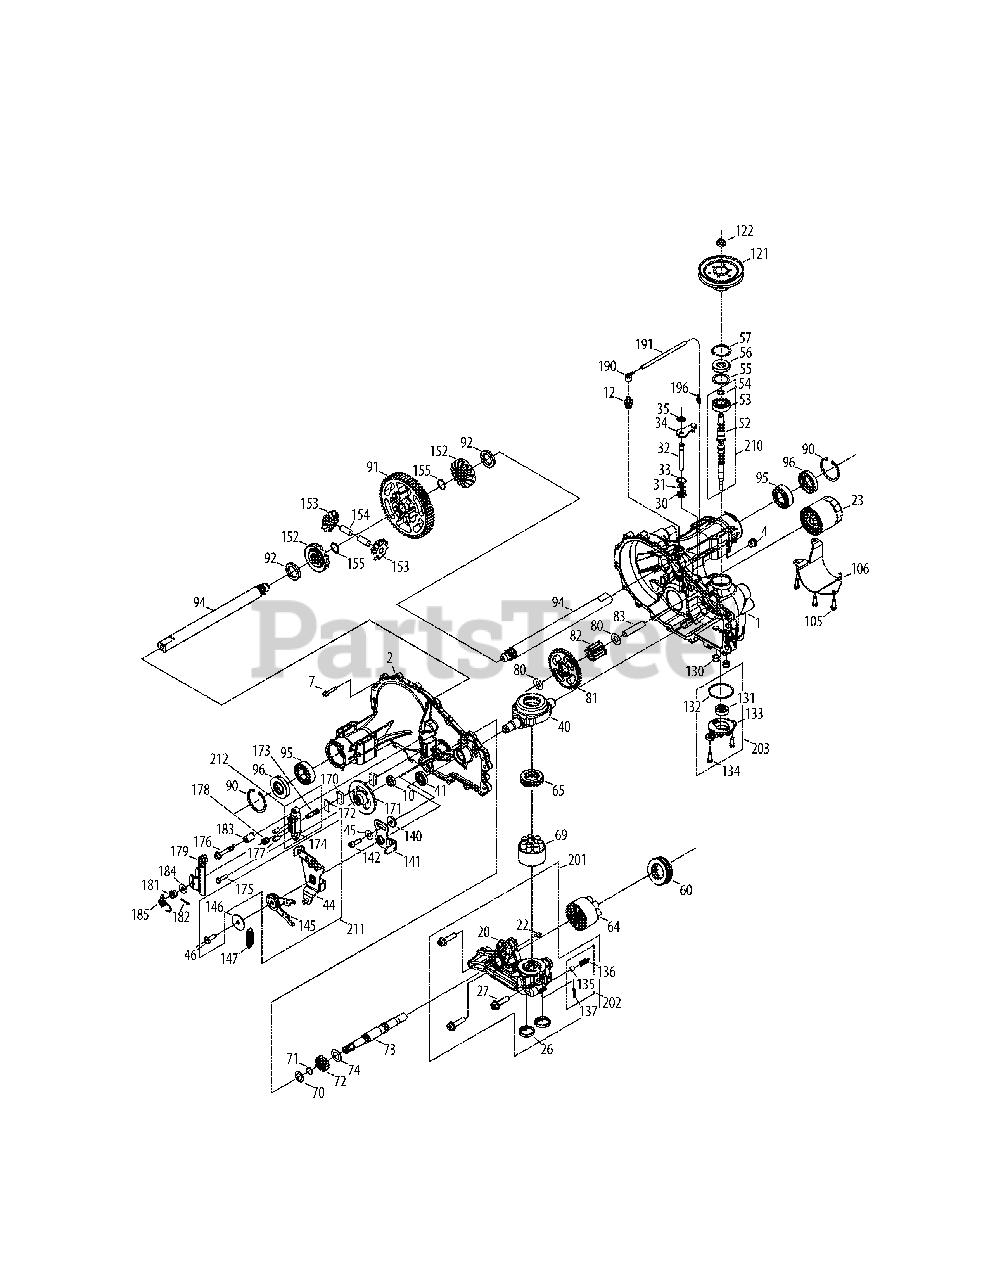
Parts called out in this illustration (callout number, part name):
1	Kit, Housing, Main
1	Housing, Main
1	Pin, Standard Headless
1	Bushing, .624 x .719 x .562
1	Bushing, .865 x .985 x .790
1	Bearing, Flange 1.0 x 1.376 x .99
2	Kit, Housing, Side
2	Housing, Side
2	Bushing, .624 x .729 x .562
2	Bushing, .865 x .985 x .790
2	Bearing, Flange 1.0 x 1.376 x .99
4	Plug, 9/16-18 (Metal)
006	Pin, Standard Headless
7	HFHCS 1/4-20 x 1.25
10	Seal, Lip .625 x 1.0
010	Seal, Lip .625 x 1.0
12	Assembly, Fitting, Metal
020	Center Section, LH, CHRG
22	Plate, Bypass
022	Plate, Bypass
23	Filter, Oil
024	Check Plug
025	Check Plug
26	Seal, Plug 1.250 x .250
026	Seal, Plug 1.250 x .250
27	HFHCS 3/8-16 x 1.5 (Patch)
027	HFHCS 3/8-16 x 1.5 (Patch)
30	Seal, Lip .375 x .75 x .25
030	Seal, Lip .375 x .75 x .25
31	Ring, Retaining .375 External
031	Ring, Ret .375 External
32	Rod, Bypass
33	Ring, Retaining .750 Internal
033	Ring, Ret .750 Internal
34	Arm, Bypass
35	Ring, Retaining .375 Internal
035	Ring, Ret .375 External
40	Trunnion, Swashplate
41	Seal, Lip 18 x 32 x 7
041	Seal, Lip 18 x 32 x 7
044	Arm, Control
45	Washer, .24 x .88 x .05
46	TWHCS 5.16-24 x 1.00 (Patch)
046	TWHCS 5.16-24 x 1.00 (Patch)
046	Screw 5/16-24 x 1.00 (Patch)
052	Shaft, Input
053	Brg, Ball 17 x 40 x 12 Open 6203
054	Ring, Ret Wire .561 ID
55	Washer, 1.23 x 1.56 x .04
56	Seal, Lip 17 x 40 x 17
056	Seal, Lip 17 x 40 x 7
57	Ring, Retaining 1.575 Internal
057	Ring, Ret 1.575 Internal
60	Bearing, Thrust
64	Assembly, Cylinder Block, 16cc
65	Bearing, Thrust Ball 30 x 52 x 13
69	Assembly, Block 7 Piston
70	Washer, .63 x 1.0 x .05
71	Ring, Retaining .625 External
071	Ring, Ret .625 x External
72	Gear, 14T
73	Shaft, Motor
74	Washer, .72 x 1.16 x .04
80	Washer, .5 x 1.0 x .03
81	Gear, 45T
82	Gear, 11T
83	Pin, Jackshaft
90	Ring, Retaining 2.06 Internal
090	Ring, Ret .206 Internal
91	Gear, 60T
92	Spacer, 1.04 x 1.65 x .22
94	Shaft, Axle 1.00 x 13.37, DD
95	Bearing, Ball 1.0 x 52 x 15
96	Seal, Lip 25 x 52 x 10 TC (Gray)
096	Seal, Lip 25 x 52 x 10 TC (Gray)
105	HFHCS 1/4-20 x .75
106	Guard, Filter, LH
121	Pulley, 4.0"
122	Hex Lock Nut 1/2-20 (Nylon Insert)
123	Screw Hex 1/4-20 x .875
130	Tube, Connecting
131	Gerorter Assembly (1.9cc/REV)
132	O-Ring - 137, .103 x 2.050
133	Cover, Charge Pump
134	Screw, Pan Head 1/4-20 x .75
135	Ball, Steel 7/16"
136	Spring, Relief .42 x .75
137	Pin, Spring .125 x .875
140	Spacer, .320 x 1.005 x .179
141	Assembly, RTN, Neutral Arm
142	SHCS 5/16-24 x 1 Patch
145	Assembly, RTN Bidirectional
146	Washer, .343 x 1.500 x .062
147	Spring, Extension RTN - 44 LBS
152	Gear, Bevel 14T Spline ID
153	Gear, Bevel 10T
154	Pin, .499 x 1.20
155	Ring, Spiral Retaining - 87
155	Ring, Sprial Ret .875
170	Puck, Brake
171	Rotor, Brake
172	Plate, Puck
173	Bolt, Square Head
174	Brake Yoke
175	Bolt, Hex Head 1/4-20 x 1 w/ Patch
176	Bolt, Hex Head 1/4-20 x 2 w/ Patch
177	Pin, Brk .31 x .73 Plated
178	Spring, Comp Brake Anti-Drag
179	Arm, Brake
181	Nut, Castle 5/16-24 PL
182	Pin, Cotter 3/32 x 3/4
183	Spacer, .26 x .57 x .87
184	Washer, .27 x .88 x .12
185	Spring, Brake Arm Bias
190	Cap, Barbed
191	Hose, .28 x .15 x 10.00
196	Fitting, Barbed
201	Kit, Center Section, LH, CHRG
202	Kit, Charge Relief
203	Kit, Charge
210	Kit, Input Shaft
211	Kit, RTN Bidirectional
212	Kit, Brake-Yoke
